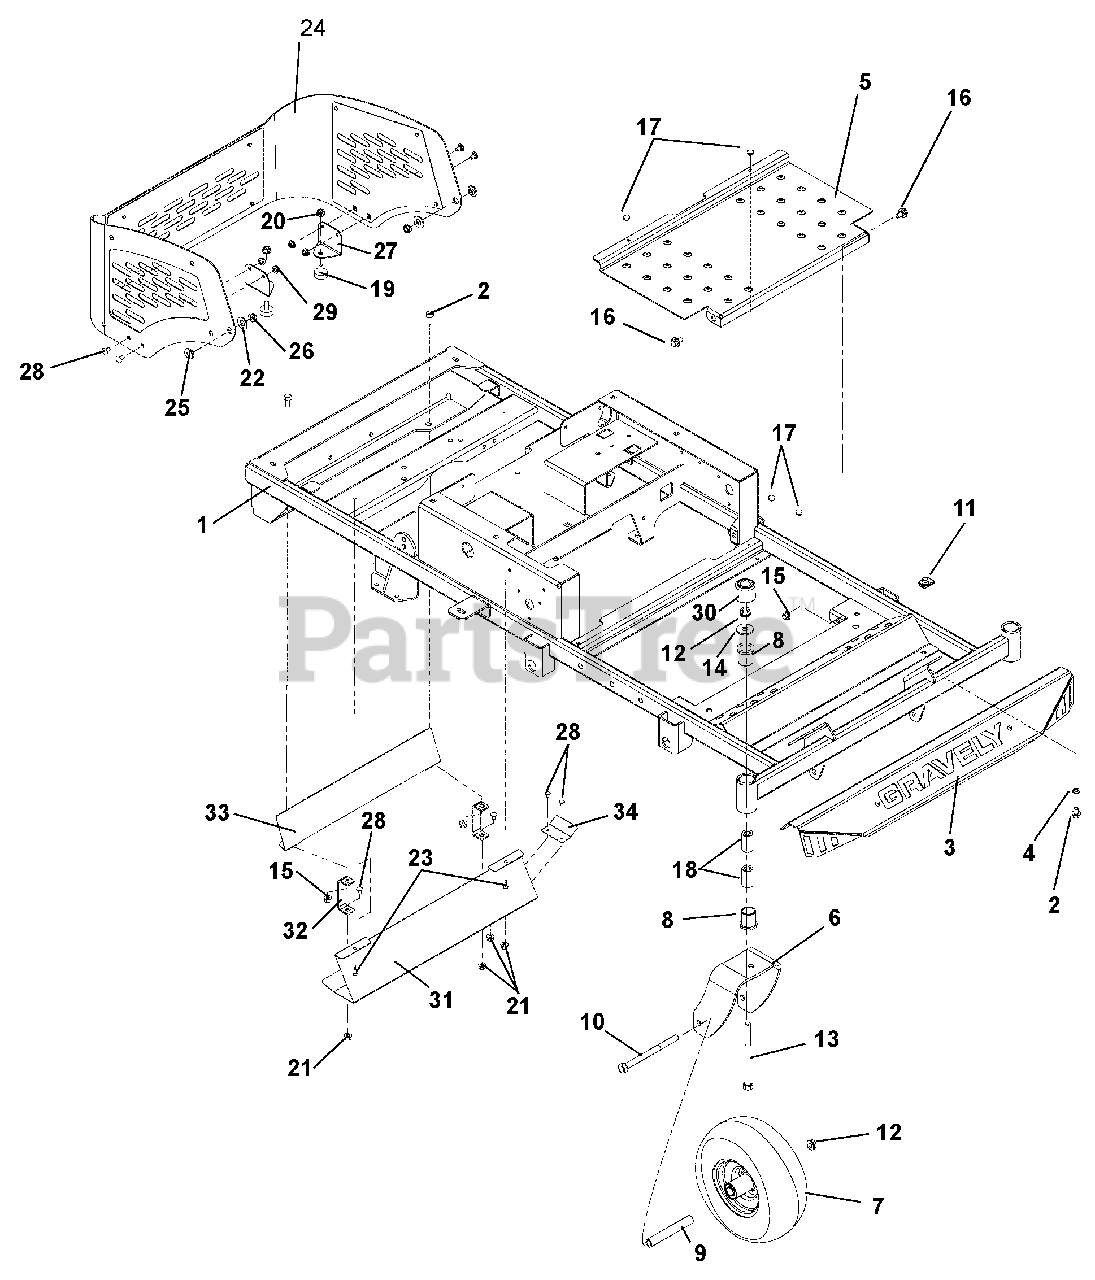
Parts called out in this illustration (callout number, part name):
1	Weldment, Frame XL
2	Bolt, Hex .38-16 x 1.00 Grade 5
3	Assembly, Foot-Rest XL
4	Washer, Locking .38 x .094 Regular
5	Deck Access Panel
6	Fork, Caster
7	Wheel/Tire Assembly, 11.0 x 4.0 x 5.0
8	Bushing, Flange 1.00 x 1.25 x 1.50 x 1.50
9	Spacer, Rolled Wheel
10	Bolt, Hex .50-13 x 6.50 Grade 5
11	Nut, Retainer .375-16 x .37
12	Nut, Locking Top Flange .50-13
13	Bolt, Hex .50-13 x 5.00 Grade 5
14	Washer, Flat Steel .511 x 1.441 x .125
15	Nut, Locking Top Flange .38-16
16	Bolt, Shoulder .375-16 x .135
17	Bumper Grommet .125 x .250 Diameter
18	Spacer, Caster Fork
19	Bumper, Rubber
20	Nut, Serrated Flange .31-18
21	Nut, Locking Top Flange .25-20
22	Washer, Flat Nylon .52 x 1.00 x .08
23	Screw, Tapping .25-20 x .50 Hex Washer Head Thread Rolling YWZ (Lubricated or Waxed)
24	Assembly, Engine Wrap XL
25	Bushing, Flange .325 x .499 x .3 x .875
26	Nut, Locking Center Flange .31-18
27	Brkt, XL Engine Wrap Foot
28	Bolt, Round Head Square Neck .25-20 x .50
29	Nut, Locking Center Flange .25-20
30	Cap, Dust
31	Guard, Muffler Heat
32	Strap, Muffler Guard
33	Shield, Hot Surface
34	Deflector, Heat Shield
